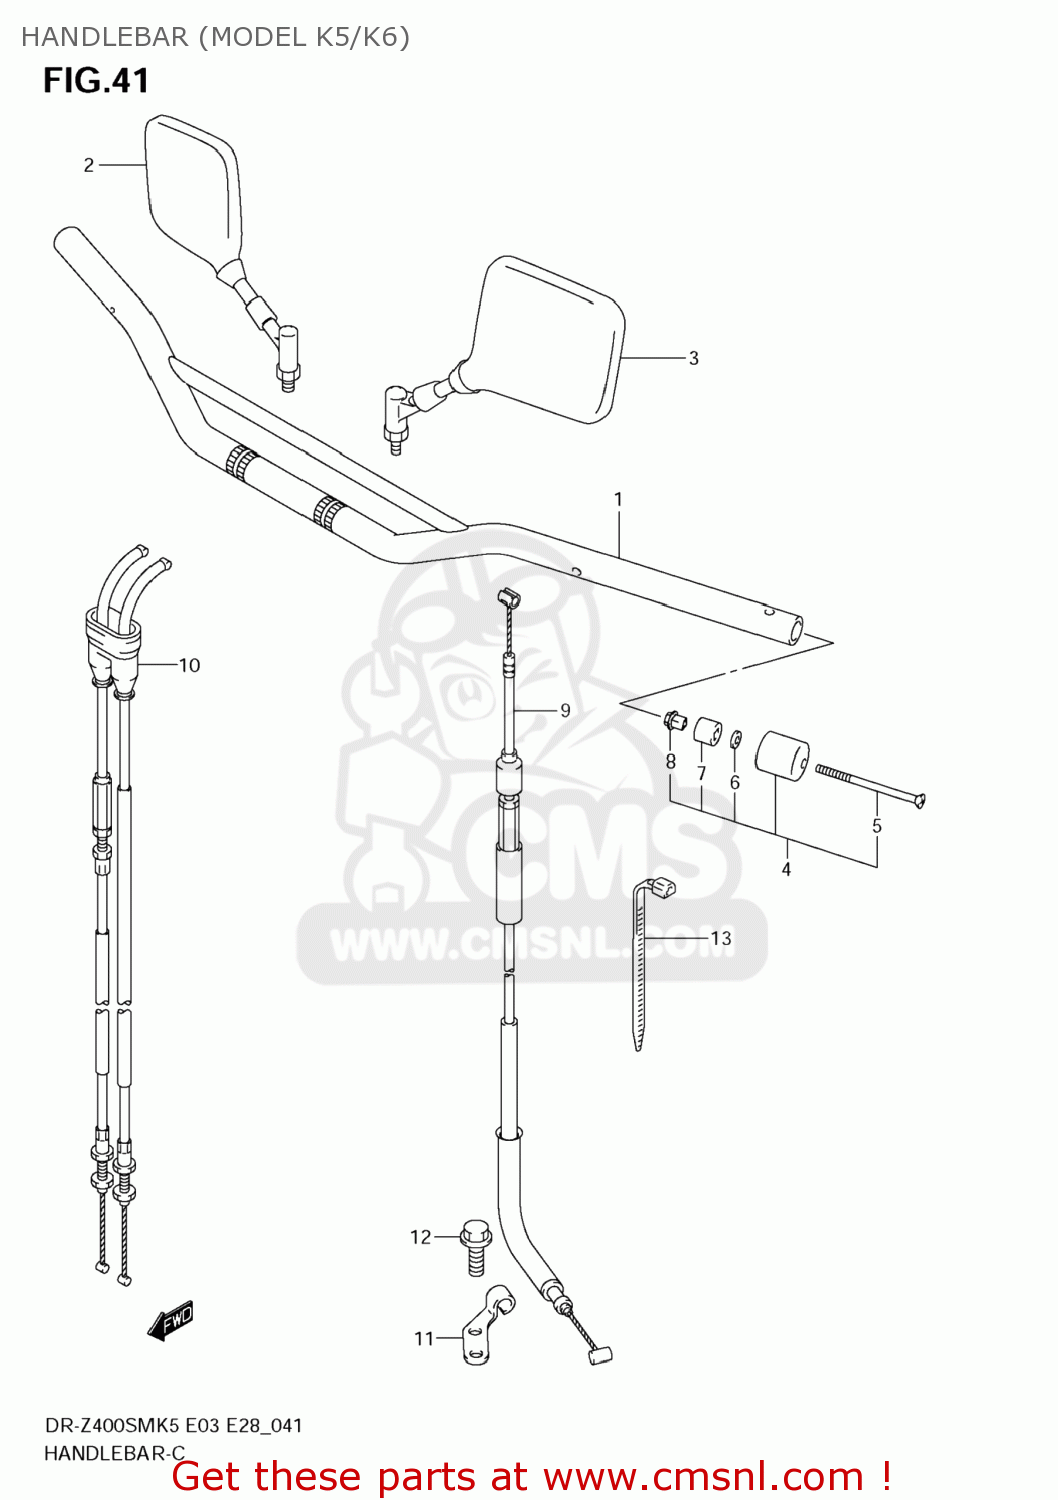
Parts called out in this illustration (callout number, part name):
1	HANDLEBAR(SILVER)
2	MIRROR ASSY,RR VIEW,R
3	MIRROR ASSY,RR VIEW,L
4	BALANCER SET,H
5	SCREW
6	WASHER(6.5X16X4)
7	EXPANDER,HANDLE BALANCER
8	NUT,HANDLE BAL
9	CABLE ASSY,CLUTCH
10	CABLE SET,THROTTLE
11	STOPPER,CLUTCH CABLE
12	BOLT
13	CLAMP(L:100)
